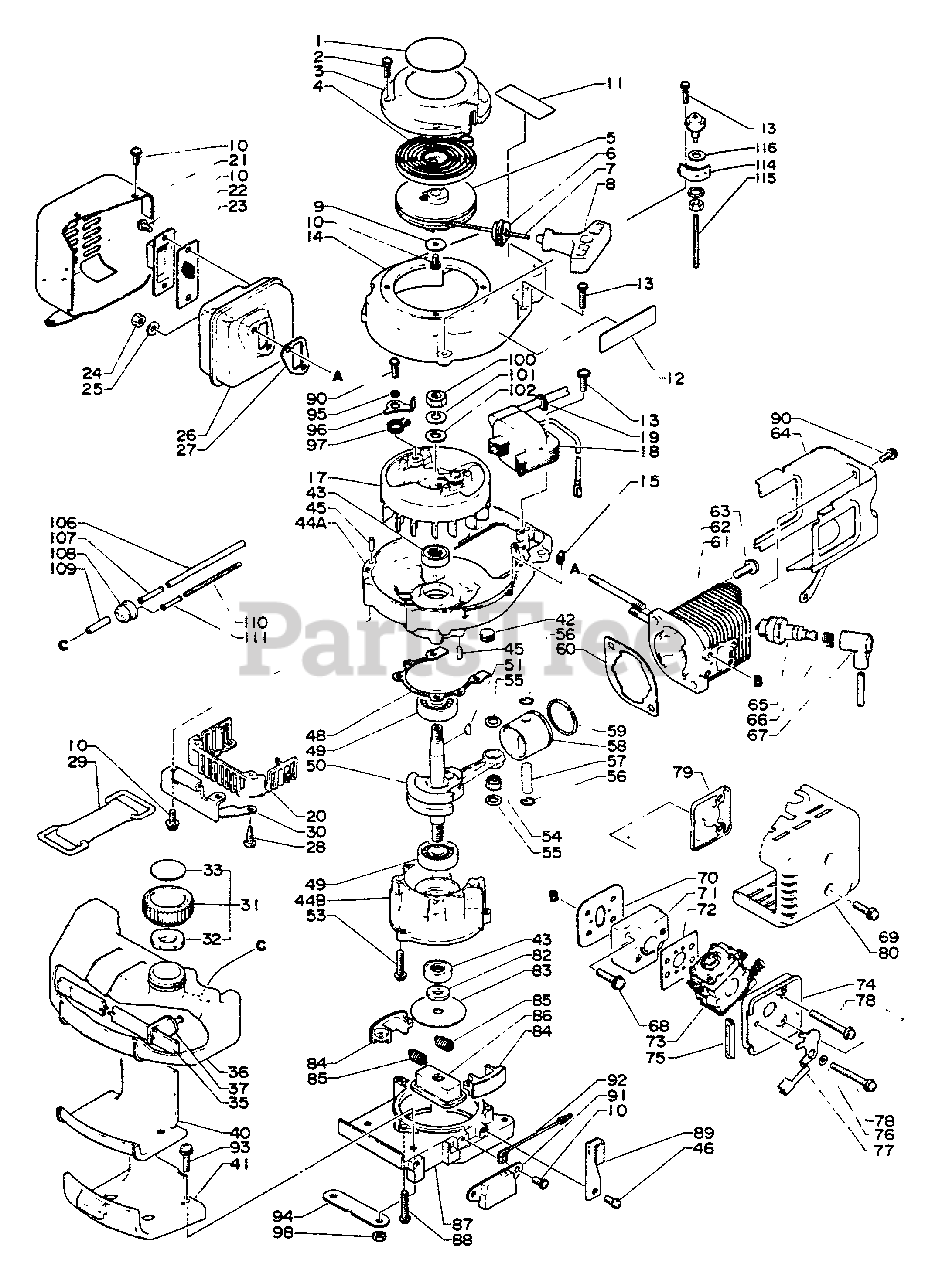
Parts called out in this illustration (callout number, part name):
1	LABEL - ECHO
2	SCREW - 4X14
3	CASE, STARTER
4	SPRING, REWIND
5	REEL, ROPE
6	GUIDE, ROPE
7	ROPE, STARTER - 3X850
8	GRIP, STARTER
10	SCREW - 4X10
11	LABEL - MODEL
12	LABEL - CAUTION
13	SCREW - 4X20
14	CASE, FAN
17	FLYWHEEL
18	COIL, IGNITION
20	SEAL, DUST
21	COVER, EXHAUST
21	MUFFLER ASSY
22	GUIDE, EXHAUST
23	SCREEN, SPARK ARRESTOR
24	LOCKNUT - 5
25	WASHER - 5
26	MUFFLER
27	GASKET, EXHAUST
28	SCREW - 4X14 -- TAPPING
29	STRAP
30	BRACKET, FUEL TANK
31	CAP ASSY
32	VENT
33	LABEL - FUEL MIX
35	SEAL, FELT
36	TANK, FUEL
37	FILTER, FUEL
40	CUSHION
41	BRACKET, FUEL TANK
42	PLUG
43	SEAL, OIL
44	CRANKCASE KIT
44A	CRANKCASE KIT
44B	CRANKCASE KIT
45	PIN - LOCATING
46	SCREW - 5X14
48	GASKET, CRANKCASE
49	BEARING, BALL - 6201
50	CRANKSHAFT ASSY
53	SCREW - 5X30
54	BEARING, NEEDLE - 8
55	SPACER, PISTON
56	RING, RETAINING
57	PIN, PISTON
58	PISTON
59	RING, PISTON
60	GASKET, CYLINDER
61	CYLINDER
63	SCREW - 6X20
64	SHIELD, CYLINDER
65	SPARK PLUG -- BM-6A
66	TERMINAL, SPARK PLUG CAP
67	CAP, SPARK PLUG
68	SCREW - 5X20
69	SCREW - 4X18
70	GASKET, INTAKE
71	INSULATOR, INTAKE
72	GASKET, INTAKE
73	CARBURETOR WA-148A
74	CASE, AIR FILTER
76	WASHER - 5
77	SHUTTER, CHOKE
78	SCREW - 5X40
79	FILTER, AIR
80	COVER, AIR FILTER
83	PLATE, CLUTCH
84	SHOE, CLUTCH
85	SPRING, CLUTCH
86	HUB, CLUTCH
87	CASE, CLUTCH
88	SCREW - 4X25
89	CLIP
90	SCREW - 5X10
91	COIL, IGNITION
92	LEAD
93	SCREW - 5X25
94	WASHER
96	PAWL, STARTER
97	SPRING, RETURN
100	NUT - 8 -- LEFT HAND
101	LOCKWASHER - 8
102	WASHER - 8
106	PIPE - 3X6X120 -- BLACK
107	CONNECTOR, PIPE
108	GROMMET
109	PIPE - FUEL
110	PIPE - FUEL
111	CONNECTOR, PIPE
115	PIPE, FUEL PUMP
116	WASHER - 10
117	RETAINER, PIPE
